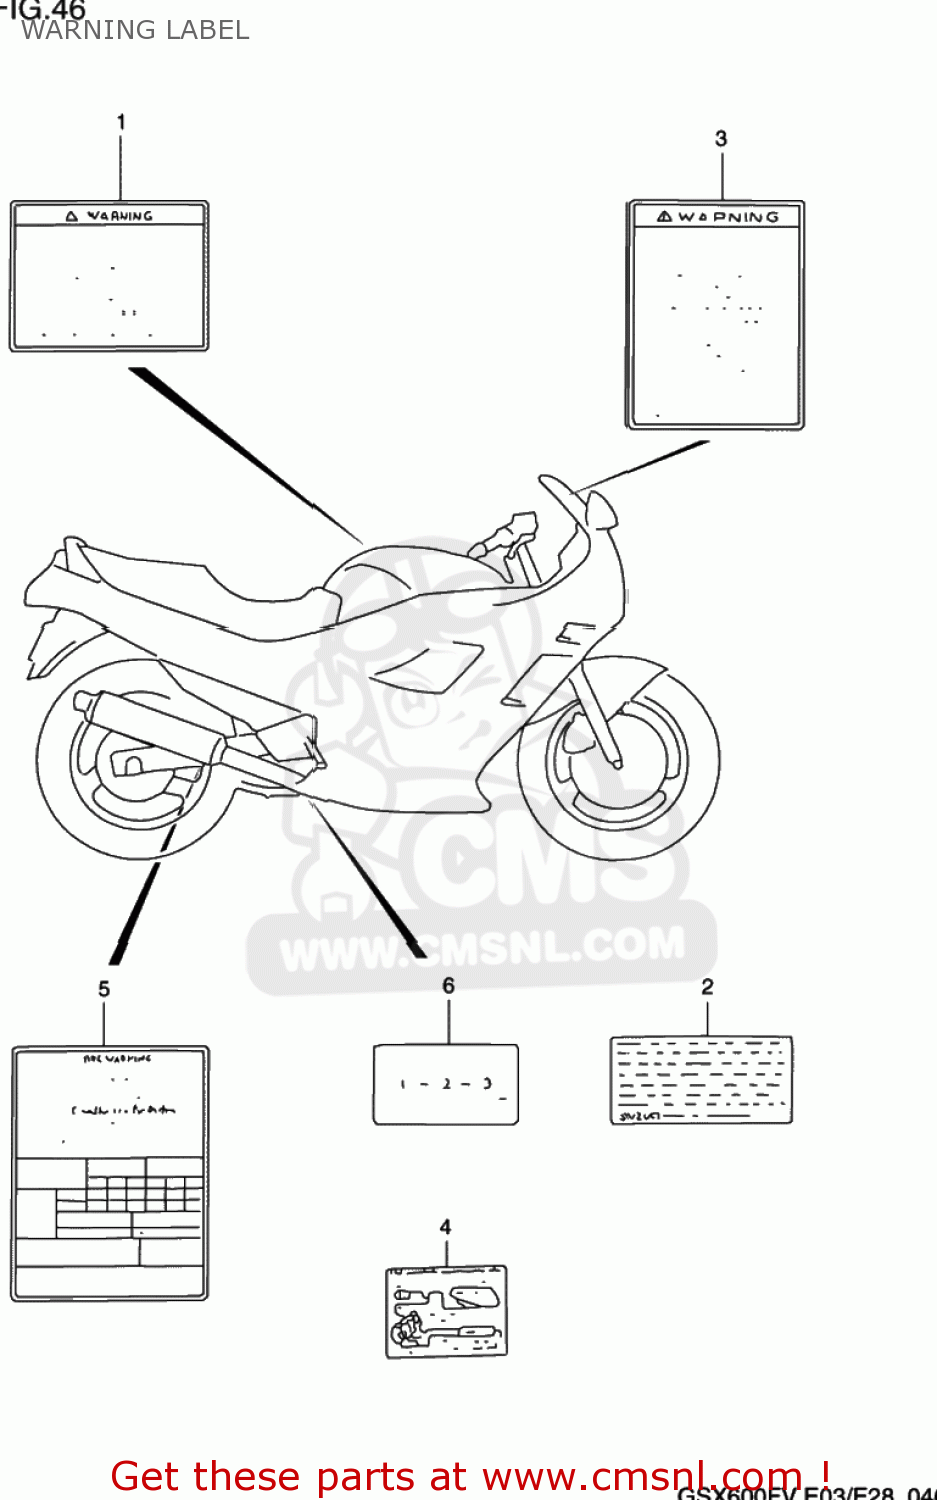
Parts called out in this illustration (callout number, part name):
1	LABEL,WARNING SAFETY
2	LABEL (MANUAL NOTICE)
3	LABEL (WARNING SCREEN)
4	LABEL (VACUUM HOSE ROUTING)
5	LABEL (TIRE AIR PRESSURE)
6	MANUAL, OWNER'S
